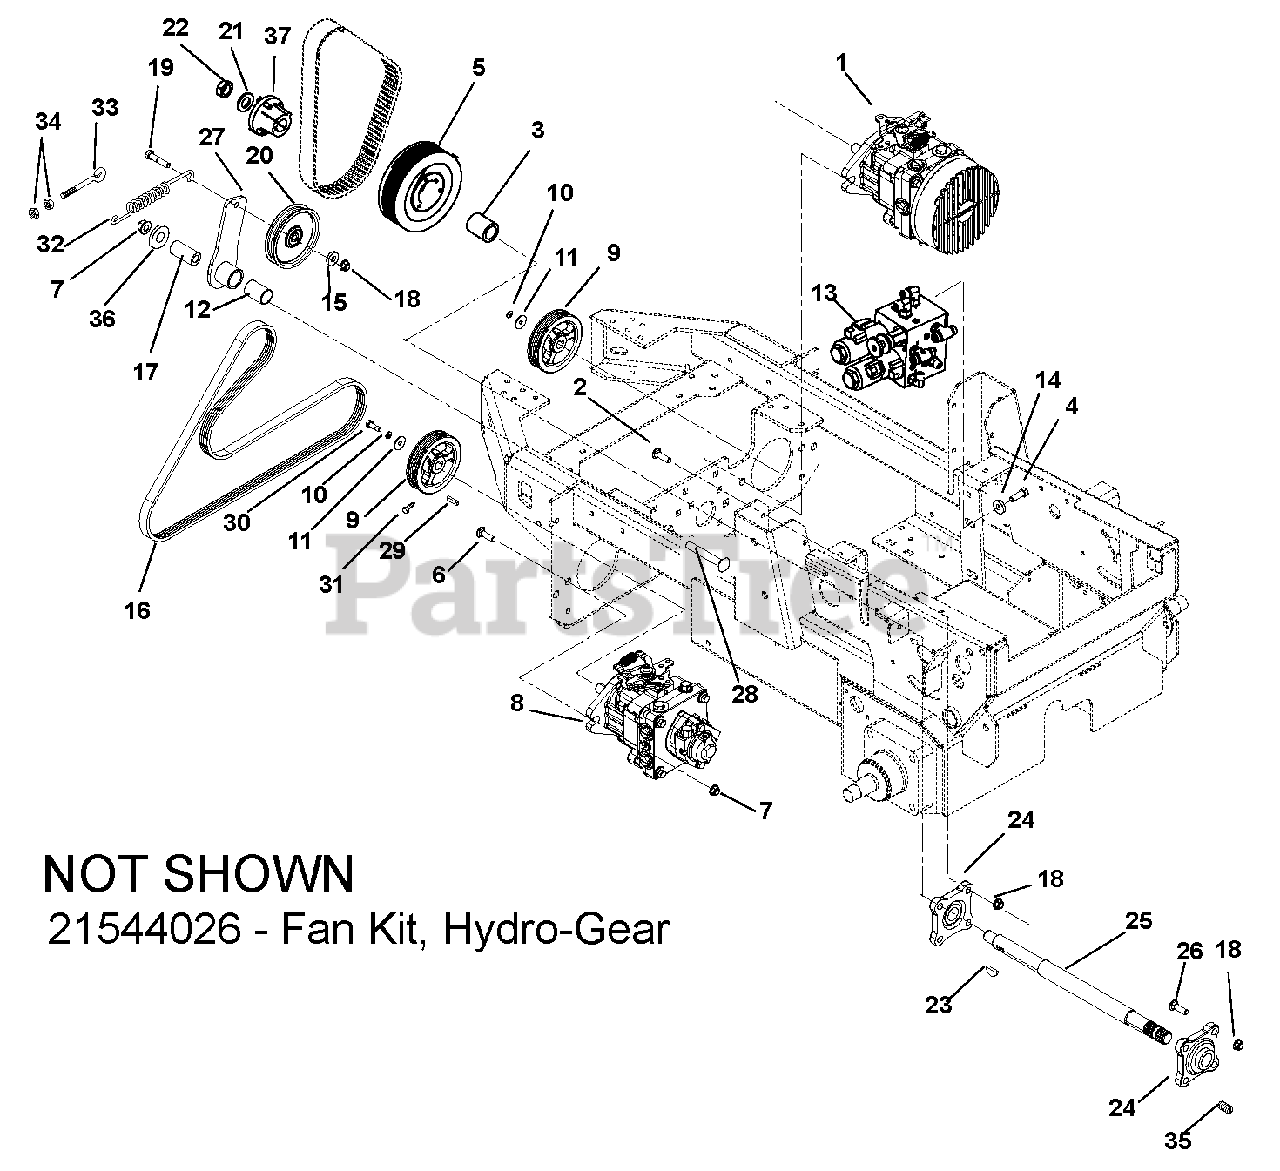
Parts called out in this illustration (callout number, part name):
1	Pump, Hydraulic BDP-21L Left Hand Rapid XZ
2	Bolt, Round Head Square Neck .38-16 x 1.25 Grade 5
3	Spacer, 1.0ID x 1.5OD x 1.81 Lining
4	Bolt, Hex .31-18X1.00 Grade 5
5	Pulley, 8G Poly V L-Section
6	Bolt, Round Head Square Neck .50-13 x 1.50 Grade 5
7	Nut, .50-13 Nyloc Flange
8	Pump, Hydraulic BDP-21L Right Hand Rapid XZ
9	Sheave, Poly V .671 x 4.125
10	Washer, Locking .25 x .06
11	Washer, Flat Steel .281 x 1.000 x .063
12	Bearing, 1.00 x 1.125 x 1.936
13	Valve, 2 Spool Mainifold Block
14	Washer, Flat Steel .344 x 1.125 x .135
15	Washer, Flat Steel .406 x .812 x .065 YWZC
16	Belt, Poly-V 69.39 (5 RIBS)
17	Bushing, Spacer .5058.500 x .999/.906 x 2.05/2.03
18	Nut, Nyloc Flange .38-16
19	Bolt, Hex .38-16 x 2.25 Grade 5
20	Idler, Flat 4.00 x .38
21	Washer, Flat-Steel .812 x 1.50 x .135
22	Nut, Jam Center Lock .75-16
23	Key, Woodruff .25 x .750 x .313 SAE91
24	Bearing, 1" ID 4 Bolt Trash Seal
25	Shaft, PTO Jack Shaft Rapid XZ
26	Bolt, Hex .38-16 x 1.25 Grade 5
27	Assembly, Idler Pivot Arm
28	Bolt, Round Head Square Neck .50-13 x 3.50 Grade 5
29	Key, Square 5 x 5 x 30MM Plain
30	Bolt, Hex M6-1 x 16
31	Screw, Socket Head .25-20 x .50 PH and Oil
32	Spring, Tension .135 x .69 x 5.75 Weldment 150
33	Bolt, Eye .375-16 x 2.50
34	Nut, Hex .38-16
35	Screw, Set .25-28 x .38
36	Washer, Flat Steel .511 x 1.44 x .125
37	Hub, Sheave
